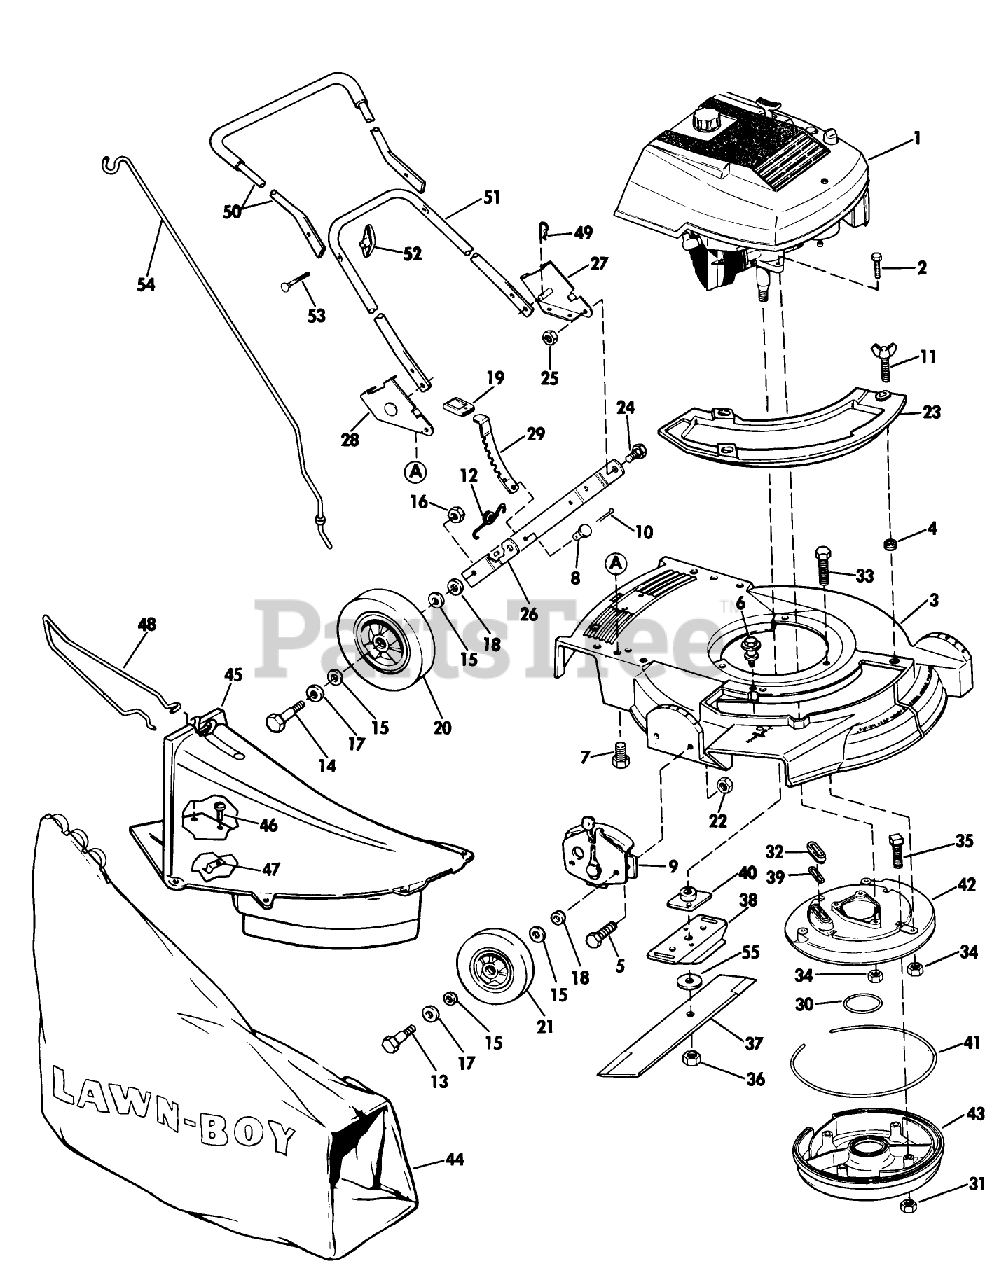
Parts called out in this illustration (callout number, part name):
11	WING SCREW LAWRE
12	SPRING N.A.S
13	BOLT WHEEL
16	LOCKNUT
18	WASHER WROUGHT
24	BOLT-SHOULDER
31	LOCKNUT E
33	SCREW V
36	NUT-BLADE
39	GASKET S
40	PLATE AND COLLAR ASM
41	Gasket Muffler (outside)
49	HAIR PIN
52	NUT-WING
54	ROD GRASSBAG
